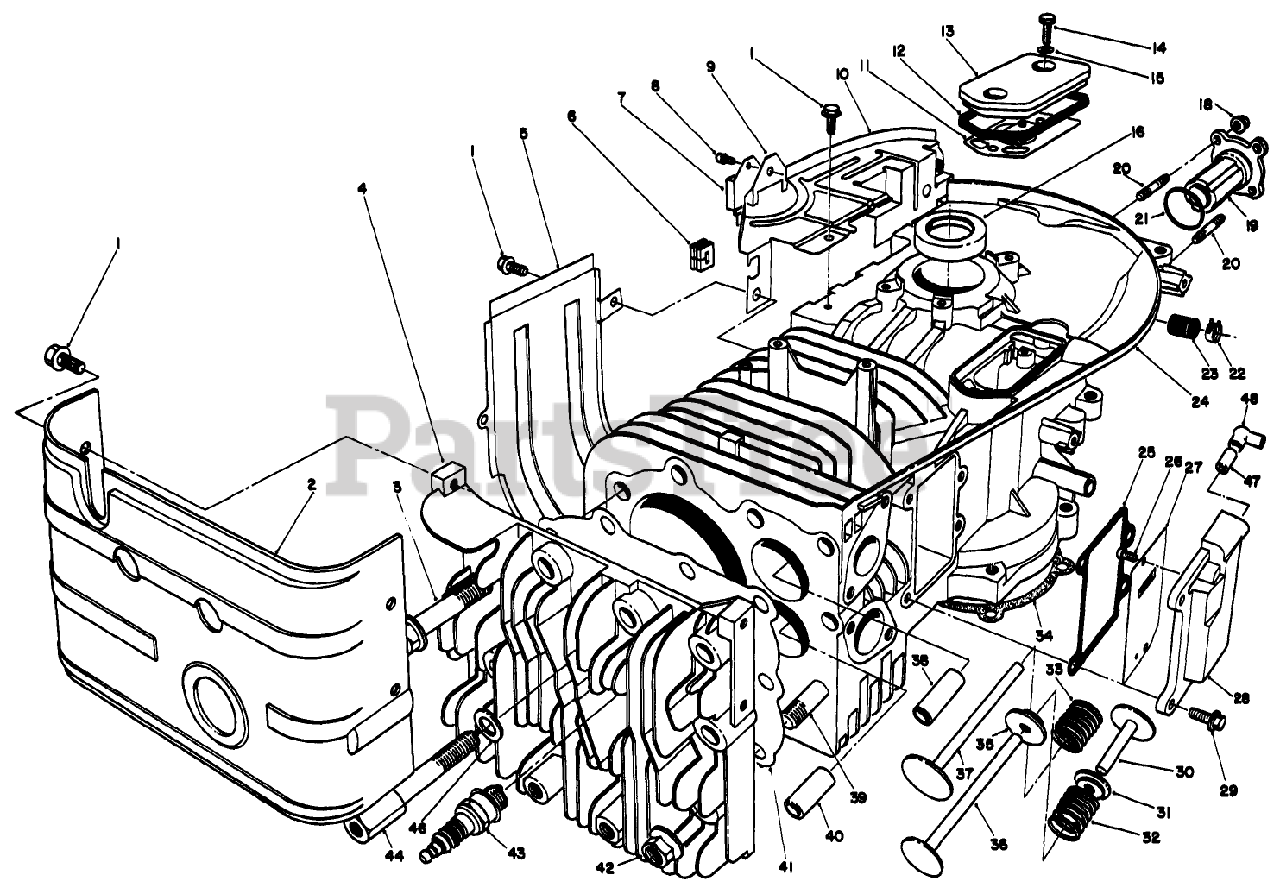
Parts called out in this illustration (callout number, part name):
1	Bolt-Flanged (6X10)
4	Cylinder Head
6	Grommet
7	Igniter
10	Fan Housing
11	Breather
16	Oil Seal
24	Crankcase Assembly
28	Cover-Valve Chamber
29	Bolt-Flanged (6X16)
31	Retainer-Spring
32	Spring-Valve
33	Spring - Valve
35	Rotator
36	Exhaust Valve
37	Intake Valve
38	Guide-Intake Valve
40	Guide-Exhaust Valve
43	Spark Plug
46	Washer
